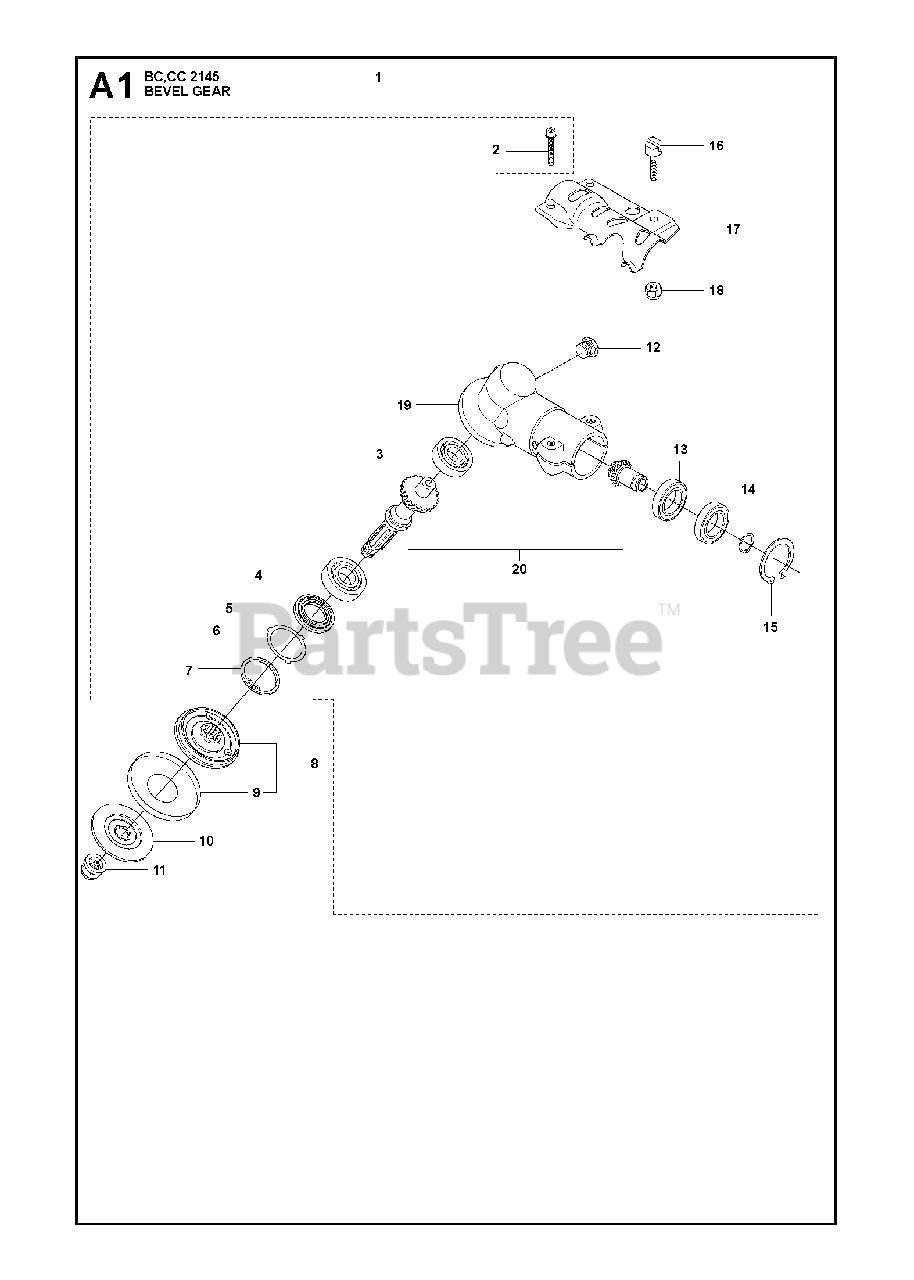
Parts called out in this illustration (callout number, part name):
1	GEAR ASSY
2	SCREW
3	BALL BEARING
4	BALL BEARING
5	SEAL
6	WASHER
7	RETAINING RING SGH 35
8	RP CARRIER
9	RP TUBE INSERT
10	SUPPORT FLANGE
11	NUT BLADE
12	PLUG
13	BALL BEARING
14	RETAINING RING SGA 15
15	RETAINING RING
17	ATTACHMENT PLATE
18	LOCKNUT M6
19	GEAR HOUSING
20	SPARE PARTS KIT
